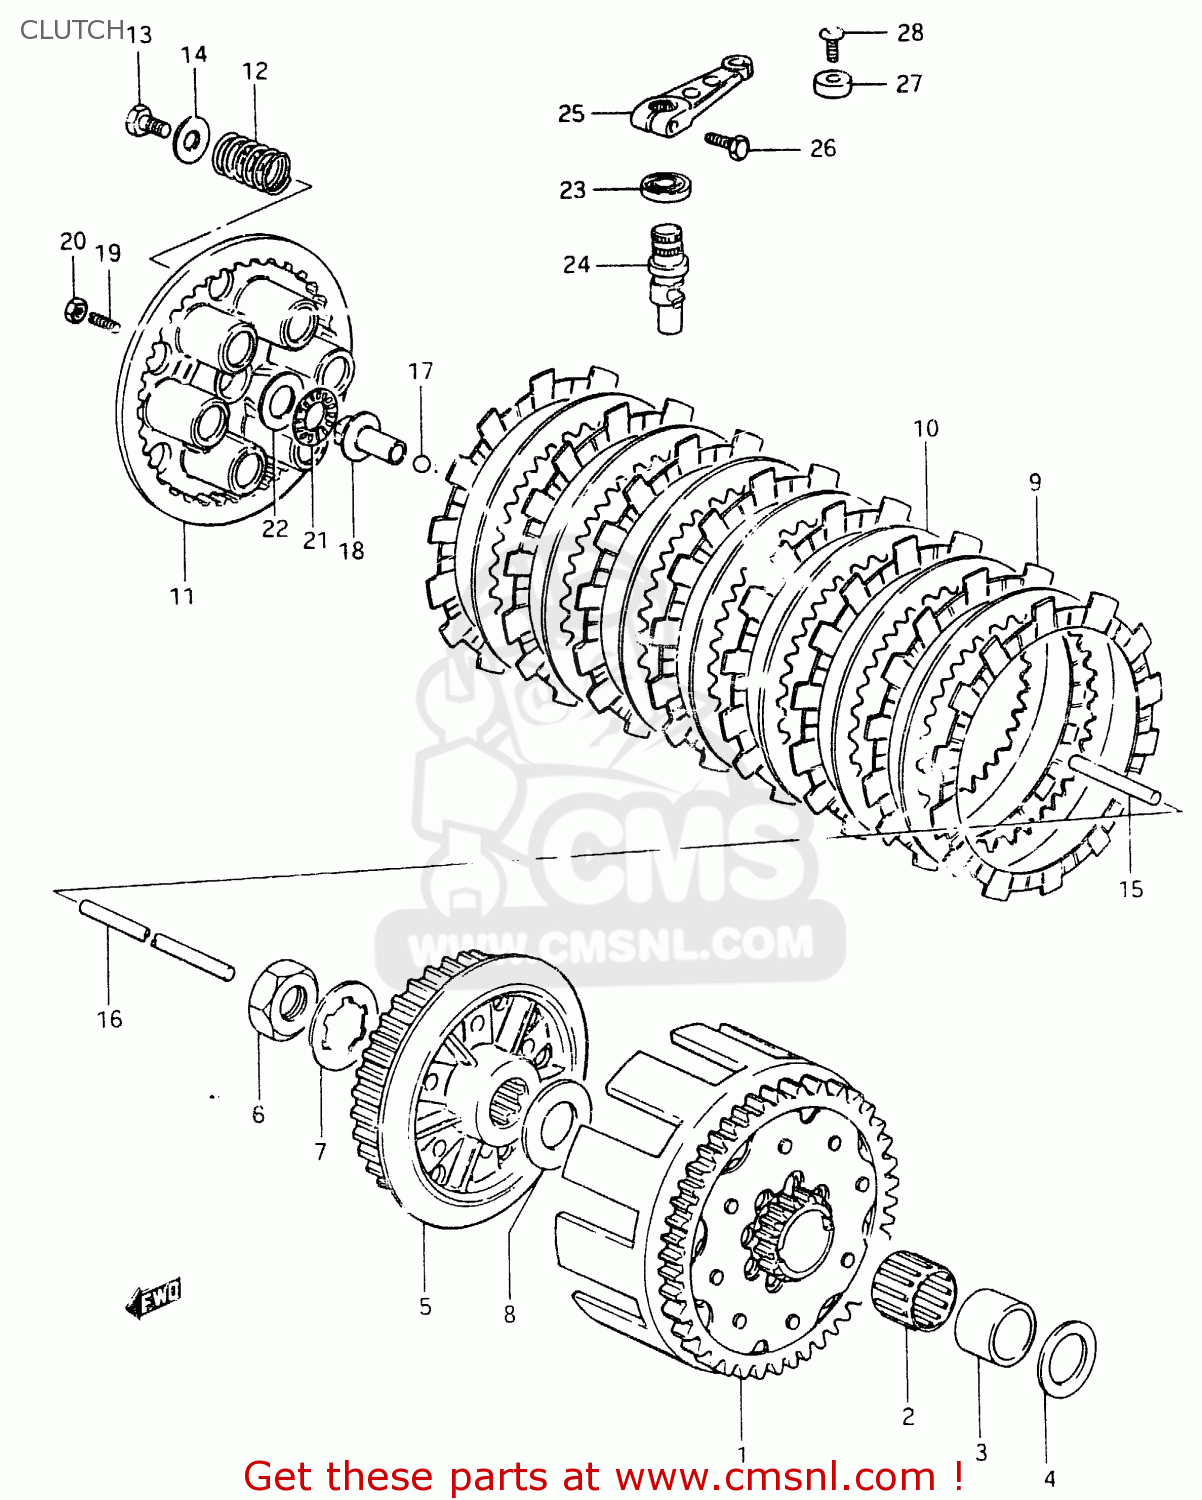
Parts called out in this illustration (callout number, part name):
1	GEAR ASSEMBLY,PRIMARY DRIVE
2	BEARING(28X33X27)
3	SPACER(22X28X27)
4	WASHER
5	HUB,CLUTCH SLEEVE
6	NUT
7	WASHER,LOCK
8	WASHER
9	PLATE,CLUTCH DRIVE (MCA)
10	PLATE,CLUTCH DRIVEN (NAS)
11	DISC,CLUTCH PRESSURE
12	SPRING
13	BOLT, UPPER
14	WASHER
15	ROD,CLUTCH PUSH NO.2
16	ROD,CLUTCH PUSH
17	BALL
18	PIECE,CLUTCH PUSH
19	SCREW
20	NUT 6MM
21	BEARING(15X28X2)
22	WASHER
23	SEAL,OIL(12X19X5)
24	SHAFT,CLUTCH RELEASE C
25	ARM,CLUTCH RELEASE
26	BOLT
27	GUIDE,CLUTCH CABLE
28	SCREW
